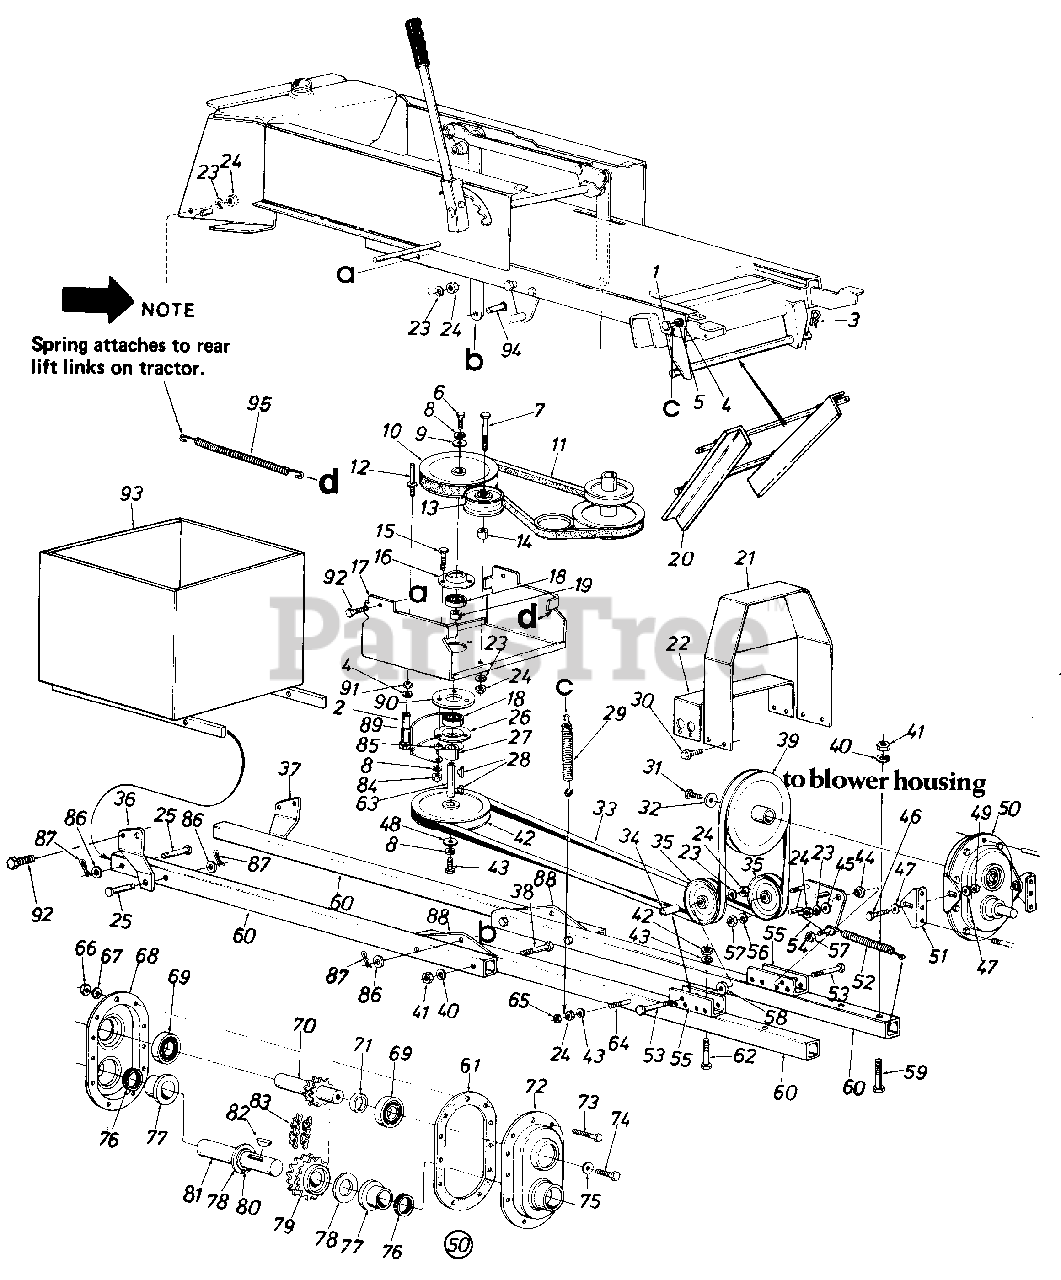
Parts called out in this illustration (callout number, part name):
1	Hex Bolt 1/4-28 x 1.50"
2	Clevis Pin Special 3/8" Dia. X 2.62" Lg.
3	Inter. Cotter Pin 1/2" Dia.
4	L.-Wash. 1/4" I.D.
5	Hex Nut 1/4-28 Thd.
6	Hex Bolt 3/8-24 x 1.0" L.
7	Hex Bolt 3/8-16 x 2.25" Lg.*
8	L.-Wash. 3/8" I.D.*
9	L.-Wash. .39" I.D. x 1.25" O.D.
10	5/8 V"-Pulley .790" I.D. x 6.50 O.D.
11	V-Belt 1/2" x 52.0" Lg.
12	Belt Guard Pin 1/4" Dia, x l.68" Lg.
13	Fl.-ldler w/flanges3.75" O.D.
14	Spacer .385" I.D. x .630" O.D. x .760" Lg.
15	Hex Bolt 5/16-24 x 1.50" Lg.
16	Open Brg. Housing 1.85" I.D.
17	Carriage Bracket
18	Ball Brg..787"I.D. xl.85" O.D.
19	Spacer 1.0" O.D. x .790" I.D. x .350" Lg.
20	Guide Bracket Ass'y.
21	Belt Cover Ass'y.
22	Belt Cover Brkt.
23	L.-Wash. 3/8" I.D.*
24	Hex Nut 3/8-15 Thd.*
25	Clevis Pin .50" Dia. x 2.75" Lg.
26	Bearing Housing 1.85" I.D.
27	Spacer .80" I.D. x 1.00" O.D. x .125" Lg.
28	Hi-Pro-Key 3/16 x 5/8"
29	Extension Spring 1.00" O.D. x 6.44" Lg.
30	Hex Wash. HD. Sf. Tap Scr. 5/16-24x .50" Lg.
31	Hex L.-Bolt 3/8-24 x 1.00" Lg.
32	Bell.-Wash. .400"I.D. x1.25" O.D.
33	V-Belt 1/2" Ax 112.0" Lg.
34	Spacer .39" I.D. x .62" O.D. x 1.74" Lg.
35	5/8" "V"-Belt Idler 4.00" O.D.
38	Hex Bolt 1/2-13 x 5.00" Lg.*
39	5/8" "V"-Pulley 1.00" I.D. x 7.50" O.D.
40	L.-Wash. 1/2" I.D.*
41	Hex Nut 1/2-13 Thd .*
42	5/8" "V"-Pullev .79"I.D. x6.5"
43	Hex Bolt 3/8-24 x 1.0" Lg.
44	Shoulder Spacer .625" I.D.
45	Fl.-Wash. .400" I.D. x1.25" O.D.
46	Hex Bolt5/16-18x .75" Lg.*
47	Bell.-Wash. .345" I.D. x .88" o b.
48	Fl.-Wash. .39' I.D. x 1.25" O.D.
49	Hex Nut 5/16-18 Thd.*
50	Comp. Chain Gear Box Ass'y.
51	Gear Box Support Brkt.
52	Extension Spring .87" Dia. x 6.00" Lg.
53	Hex Bolt 3/8-16 x 3.0" Lg. (Grade 8)
56	Fl.-Wash. .385"I.D. x .87 O.D.
57	Hex Ins. L.-Nut3/8-24Thd.
58	Fl.-Wash. .400" I.D. x 1.25" O.D. x .157 Thk.
59	Hex Bolt 1/2-13 x 3.00" Lg.*
62	Hex Bolt 3/8-16 x 3.0" Lg. (Grade 8)
63	Shaft-.787 " Dia. x 3.81 " Lg.
64	Hex BoIt 3/8-16 x 3.25" Lg.*
65	Hex Cent. L.-Jam Nut 3/8-16 Thd.
66	Hex Nut 1/4-28 Thd.
67	Spr.-Wash. .270" I.D. x .57" O.D.
68	Gear Hsg. Half-L.H.
69	Ball Brq. 1.00"I.D. x2.00" O.D.
70	11-2x .5 Pitch-Sprkit.ShaftAss'y.
71	Spacer 1.00" I.D. x 1.18" O.D. x .440 Lg.
72	Gear Hsg. Half-R.H.
73	Hex Bolt 1/4-28 x 1.00" Lg. (Grade 5
74	Hex L.-Bolt 3/8-24 x 1.00" Lg.
75	Bell.-Wash. .400" I.D. x 1.25" O.D.
76	Oil Seal 1.25" x 1.75" O.D.
77	Flange Brg. 1.252" I.D.
78	Fl.-Wash. 1.25" I.D. x2.00" O.D
79	DBL Sprkt. 19-2 Teeth x .500" Pitch
80	Snap Ring for 1.25" Dia. Shaft
81	Gear Shaft 1.25" Dia. x 6.0" Lg.
82	#A Hi-Pro Key 1/4 x 7/8" Dia. I
83	40-2 Chain 1/2" Pitch x 25 Links
83	Master Link #40 Type IV
84	Hex Nut 5/16-24 Thd.*
85	Spacer .380" I.D. x .625" O.D. x .227" Lg.
86	Fl.-Wash. .510" I.D. x 1.0" O.D.
87	Inter. Cot.-Pin 1/2" Dia.
90	Spindle Spacer
91	Hex Nut 1/4-20 Thd.
92	Hex Bolt 3/8-16 x 1.0" Lg.-Gr. 5
93	Weight Box Ass'y.
95	Ext. Spring
